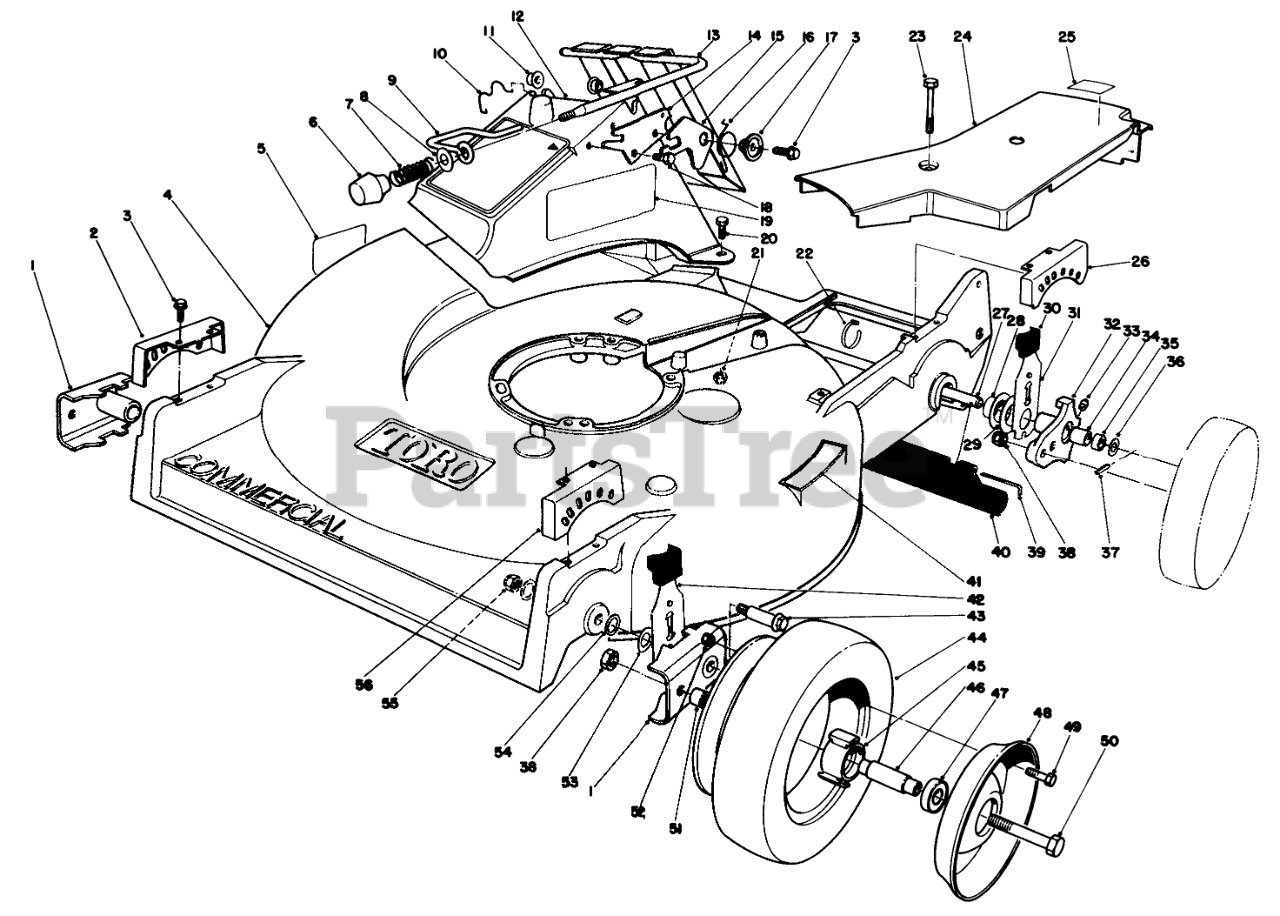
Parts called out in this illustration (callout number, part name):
1	ARM-PIVOT, FRONT
2	QUADRANT-FRONT, RH
3	SCREW-HWHTF
4	Housing-Commercial (Incl. Ref. #5,41)
5	DECAL-DANGER
7	COMPRESSION SPRING
8	WASHER-FLAT
9	DOOR LATCH
10	DOOR RETAINER
11	BUSHING-NYLON
12	DISCHARGE CHUTE B
13	DOOR & HANDLE WA
14	DOOR LATCH PLATE
15	SAFETY LATCH
16	TORSION SPRING
17	DOOR SPACER
18	SCREW-HWH
19	DECAL SAF INST
20	SCREW-HH
21	NUT-LOCK, NI
22	TIE-CABLE
23	SCREW-HHFTF
24	Belt-Cover
25	LABEL-GREASE, HP
26	QUADRANT-REAR, LH
27	SHAFT-AXLE, REAR
28	CAP-END
29	WASHER
30	KNOB-ARM
31	Spring Arm Assembly-Rear
32	PIVOT ARM ASM
33	FITTING-GREASE
34	BUSHING
35	BUSHING
36	WASHER-PLAIN
37	PIN-SPIROL
38	NUT-LOCK, NI
39	ROD-SHIELD
40	SHIELD-TRAILING
41	STEP PAD DECAL
42	Spring Arm Assembly Front
43	WHEEL BOLT
45	HUB-BEARING
46	SPACER-BEARING
47	BEARING-WHEEL
48	Wheel-Half
49	SCREW-HHF
50	SCREW-HH
51	SPACER-WHEEL
52	NUT-LOCK, NI
53	Washer-Pivot
54	WASHER
55	Nut
56	QUADRANT-FRONT, LH
